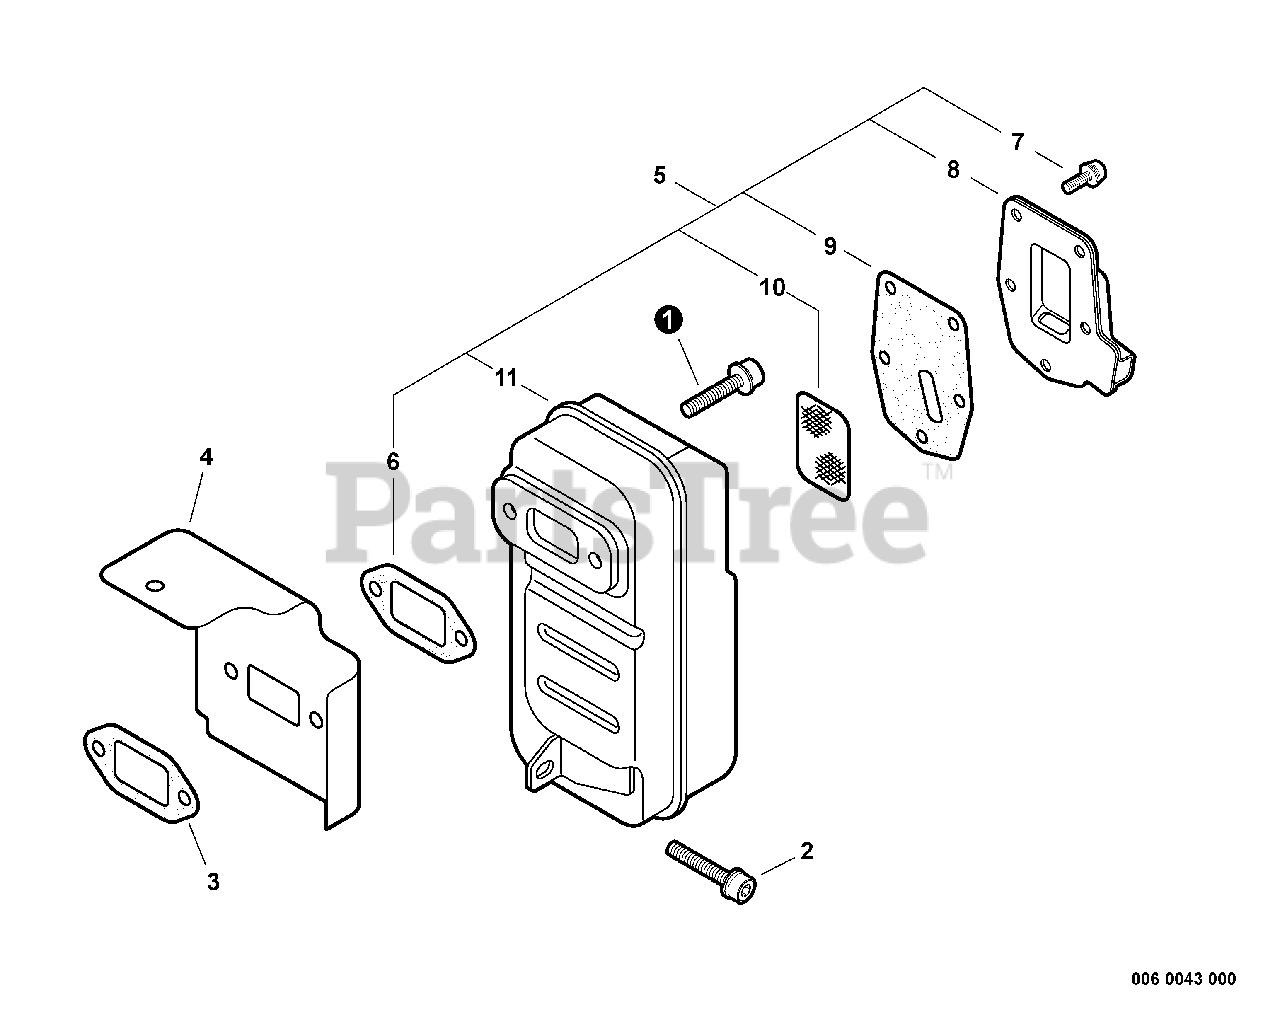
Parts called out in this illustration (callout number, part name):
1	BOLT 6×20
2	BOLT 5×20
3	GASKET, EXHAUST
4	COVER, CYLINDER
5	MUFFLER ASSY
6	GASKET, EXHAUST
7	SCREW 4×10
8	GUIDE, EXHAUST
9	GASKET, EXHAUST
10	SCREEN, SPARK ARRESTER
11	MUFFLER
